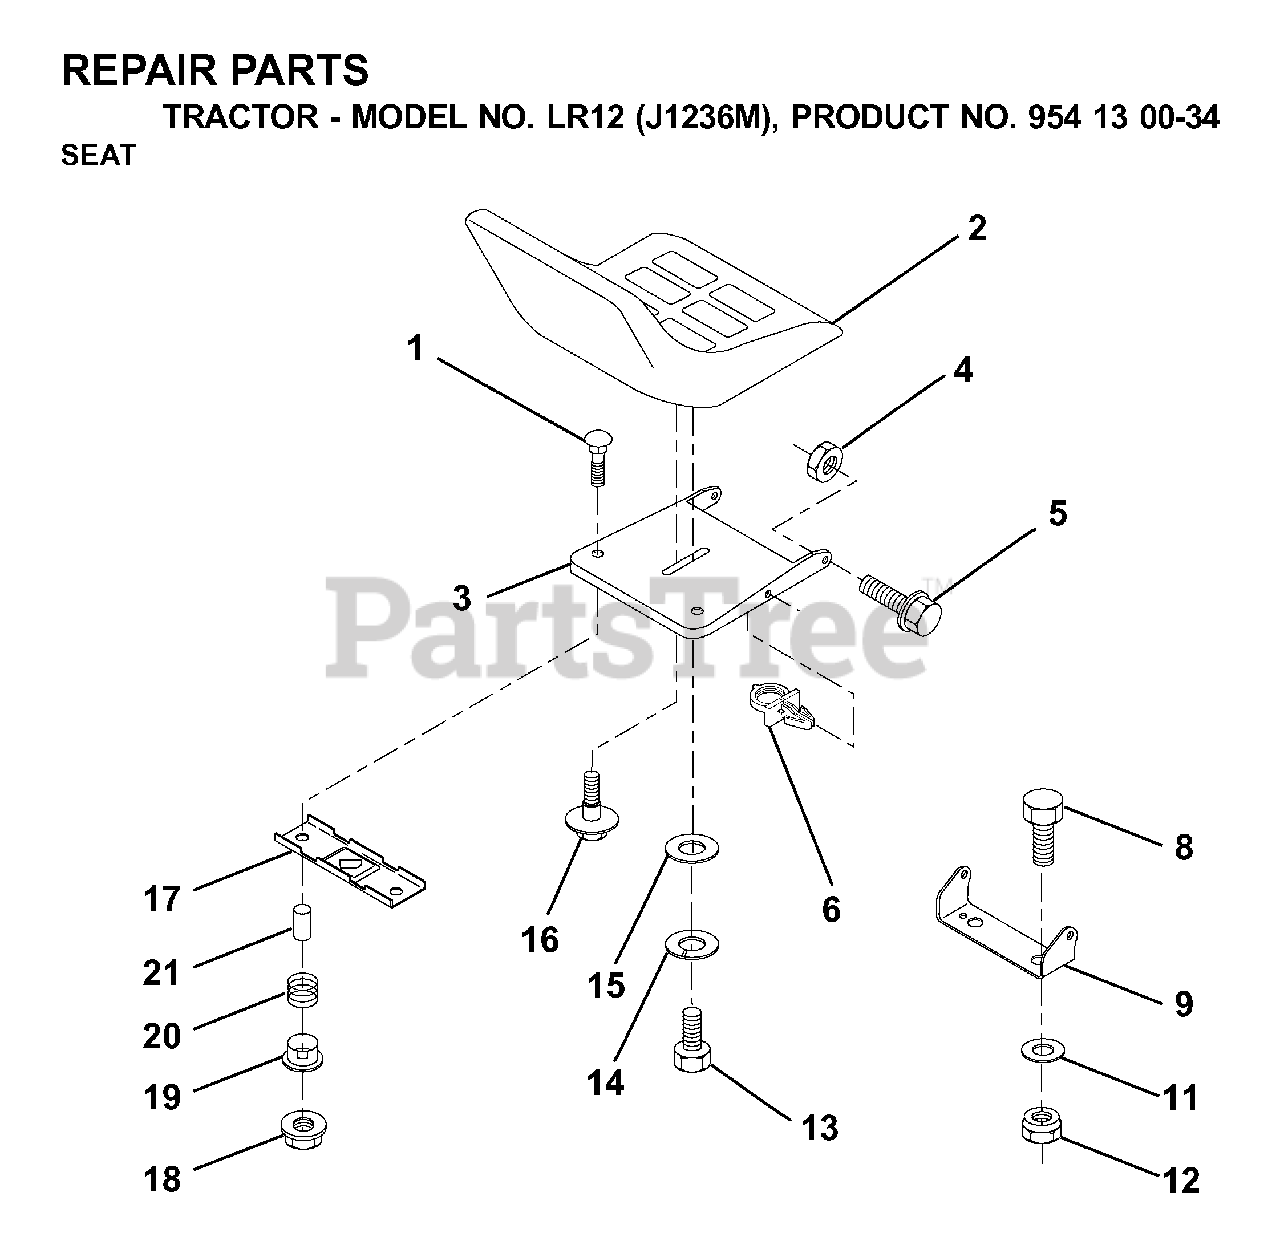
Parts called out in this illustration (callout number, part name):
1	BOLT.ROUND.HEAD.SQUARE.NECK
2	SEAT
3	PAN, SEAT
4	NUT.71038.31-18.HEX.NYLOCK
5	BOLT.SHOULDER.5/16-18
6	PUSH CLIP
8	BOLT
9	SEAT PIVOT BRKT
11	WASHER 12/32X2X10GA
12	NUT
13	BOLT
14	LOCKWASHER
16	BOLT,SHOULD
17	BRKT SWITCH
18	NUT T
21	SPACER SPLIT 28X.96
